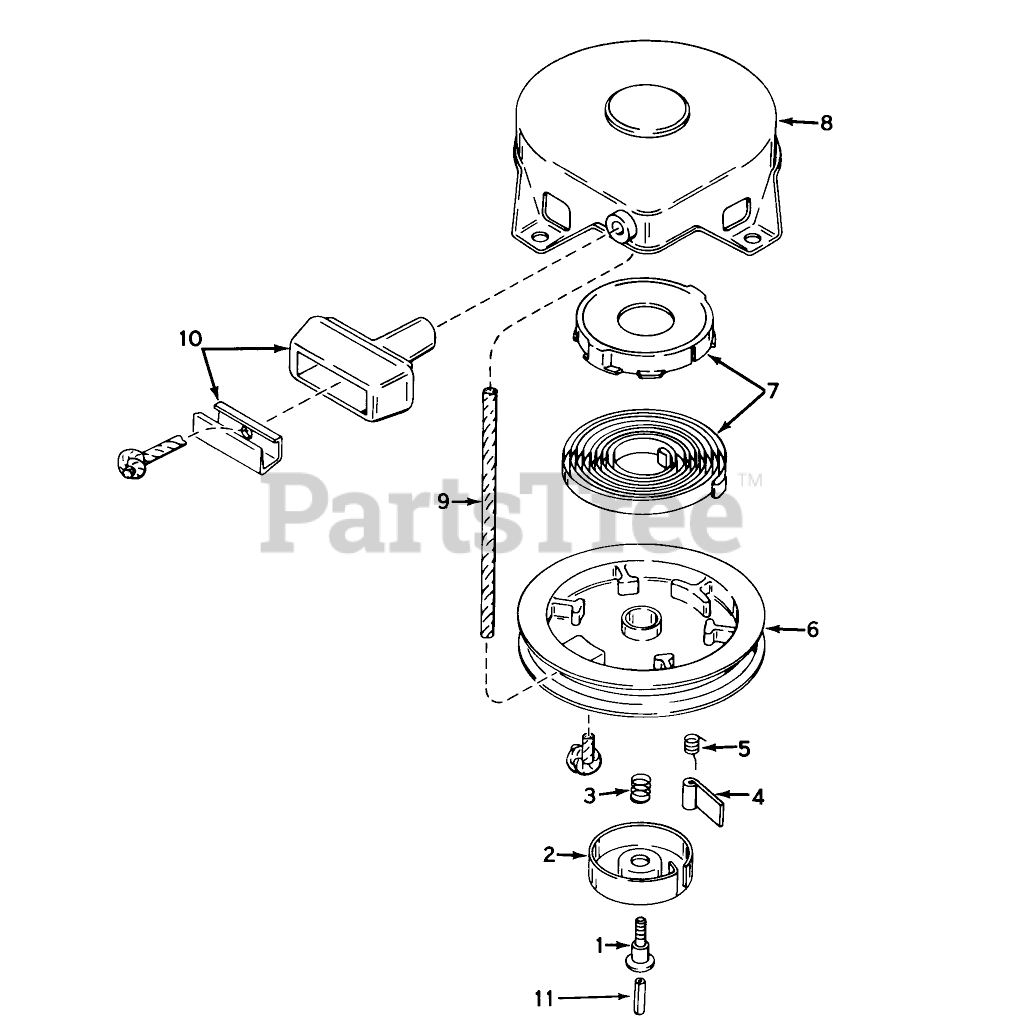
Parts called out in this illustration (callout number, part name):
1	Screw
2	Retainer
3	Spring-Brake
4	Dog-Starter
5	Spring-Dog
6	Pulley
7	Spring Keeper Assy
8	STARTER HOUSING ASSY
9	Rope Starter
10	Assy., Starter
11	Centering
